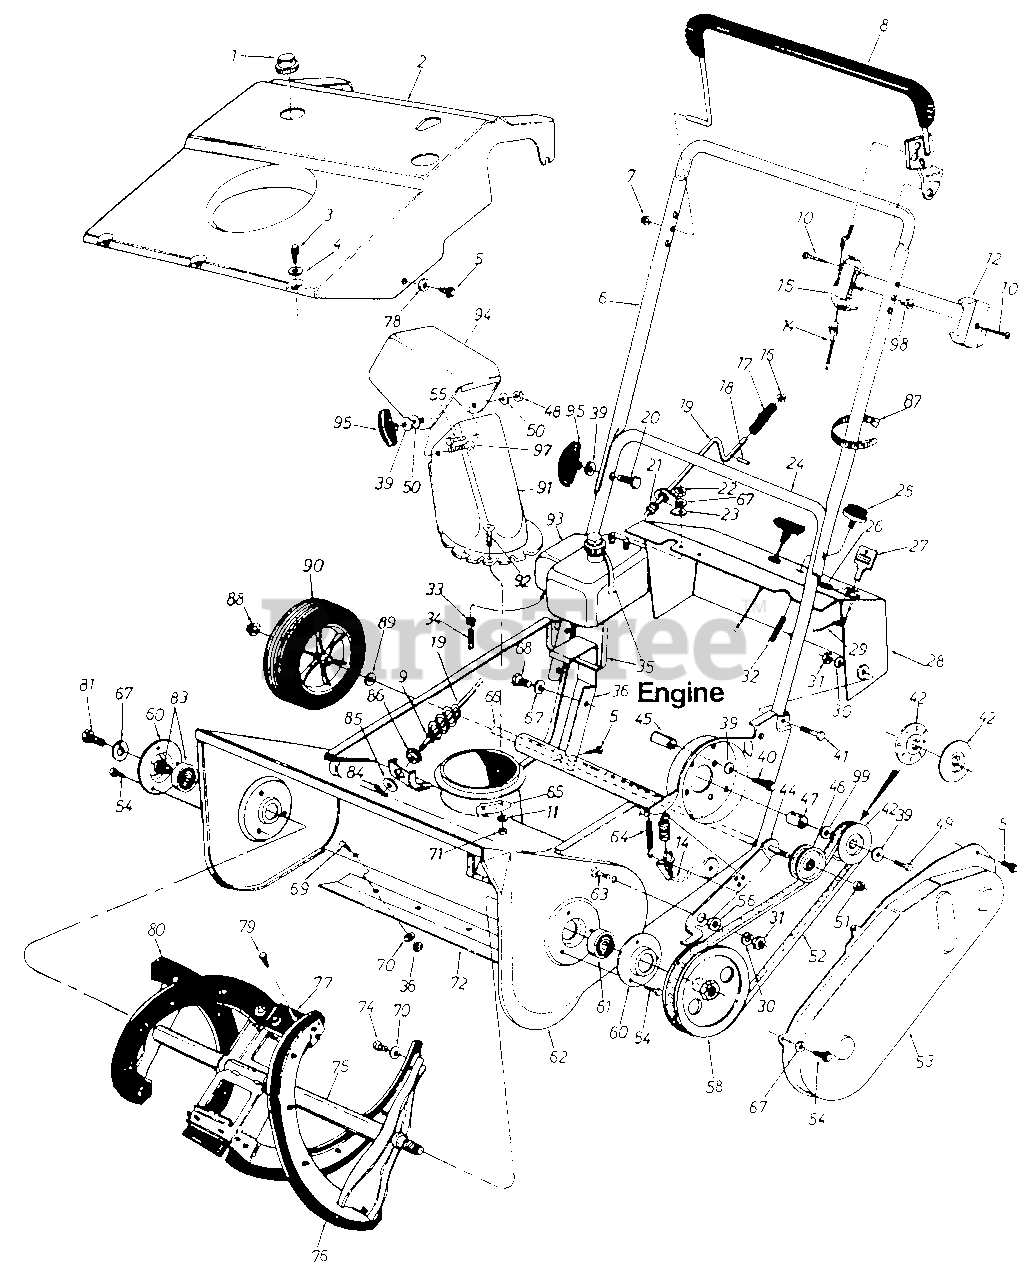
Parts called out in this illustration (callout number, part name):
1	Gas Tank Cap
2	21" Shroud
3	Hex B-Tap Scr. #10 x .38"
4	Spr.-Wash. .206" I.D. x .448"
5	Hex L-Wash. Hd. AB-Tap 1/4 x.62" Lg.
8	Control Handle Ass'y.--L.H.
9	Fl-Wash. .385" I.D. x .62"
10	Truss Mach. Hi-B Tap Scr. #12 x 1.5" Lg.
11	Fl-Wash. 1/4" I.D.
12	Control Panel Half
14	Clutch Cable 35II Lg.
15	Control Panel Half
16	Push Cap 318 Rod
17	Knob--318 Dia. Hole
18	Roll Pin 118" Dia. x .63" Lg.
19	Chute Crank Ass'y.
20	Curved Carriage Bolt 5/16-18 x 1.75" Lg.
21	Chute Crank Grommet
22	Hex Nut 1/4-20 Thd.
23	Upper Chute Crank Brkt.
24	Lower Handle
25	Primer
26	Plastic Plug
27	Plastic Key (Tech. Eng.)
28	Dash Panel Ass'y.
29	Ignition Wire
30	L-Wash. 5116" I.D.
31	Hex Nut 5/16-18 Thd.
32	Primer Hose--11" Lg.
33	Hose Clamp--.406" Dia.
34	Gas Line--9" Lg.
35	Cable Tie--17.75" Lg.
36	Engine Support Brkt.
38	Hex Jam Nut 1/4-20 Thd.
39	Bell-Wash. 345II I.D. x 88
40	Hex Bolt 5/16-18 X 1 5 Lg.
41	Hex Bolt 5/16-18 X 1 5 Lg.
42	318II "V"-Pulley Half .625" I.D. x 6.0" O.D.
44	Idler Brake Brkt. Ass'y.
45	Spacer 325II I.D. x .625" O.D. x .875"
46	Fl-ldler w/Flanges .212" O.D.
47	Spacer 635II I.D. x .89" O.D. x .57"
48	Hex L-Nut 5/16-18 Thd.
49	Hex Bolt 5/16-24 X .75" Lg.
50	Fl-Wash. .344" I.D. x 1.25"
51	Hex Patch L-Nut 3/8-24 Thd.
52	"V"-Belt
54	Hex B-Tap Scr. l/4'' X .38" Lg.
55	Truss Mach. Scr. 5/16-18 x .75"
56	Shld. Spacer .50" Dia. x .27"
58	1/2" "V"-Pulley 1/2-20 L.H. x 6"
62	21" Blower Hsg. Ass'y.
63	Truss Mach. Scr. 5/16-18 x .75" Lg.
64	Extension Spring 1.12" Lg.
65	Chute Flange Keeper
66	Wheel Axle Tubing
67	L-Wash. 1/4" I.D.
68	Hex Wash. S-Tap Scr. 1/4-20 x. 50" Lg.
69	Carriage Bolt 1/4-20 X .50"
70	Fl-Wash. .281" I.D. x .73"
71	Hex L-Nut 1/4-20 Thd.
72	Shave Plate
74	Hex Wash. B-Tap Scr. 1/4 x .62"
75	Auger Ass'y. 21"
76	Rubber Spiral--L.H.
77	Rubber Paddle
78	Fl-Wash. .218" I.D. x .62"
79	Hex Wash. B-Tap Scr. #10 x .62" Lg.
80	Rubber Spiral--R.H.
81	Hex Wash. TT-Tap Cl-Scr. 1/4-20 X .75" Lg.
83	Kit--Bearing and Collar
84	Cotter Pin 3/32" Dia. x .75"
85	Fl-Wash. .390" I.D. x 1.50"
86	Hex Bushing .385" I.D.
87	Cable Tie
88	Push Cap 1/2" Dia.
89	Fl-Wash. .510" I.D. x 75n
90	Wheel & Tire Ass'y. 6 X 1.5
91	Lower Chute
92	Truss Mach. Scr. 1/4-20 X .75"
93	Fuel Tank--Two Qt.
94	Upper Chute
95	Knob Handle Ass'y.
97	Carriage Bolt 5/16-18 X 1"
98	Control Disc Pin
99	Fl-Wash. .635" I.D. x 1.04" O.D.
